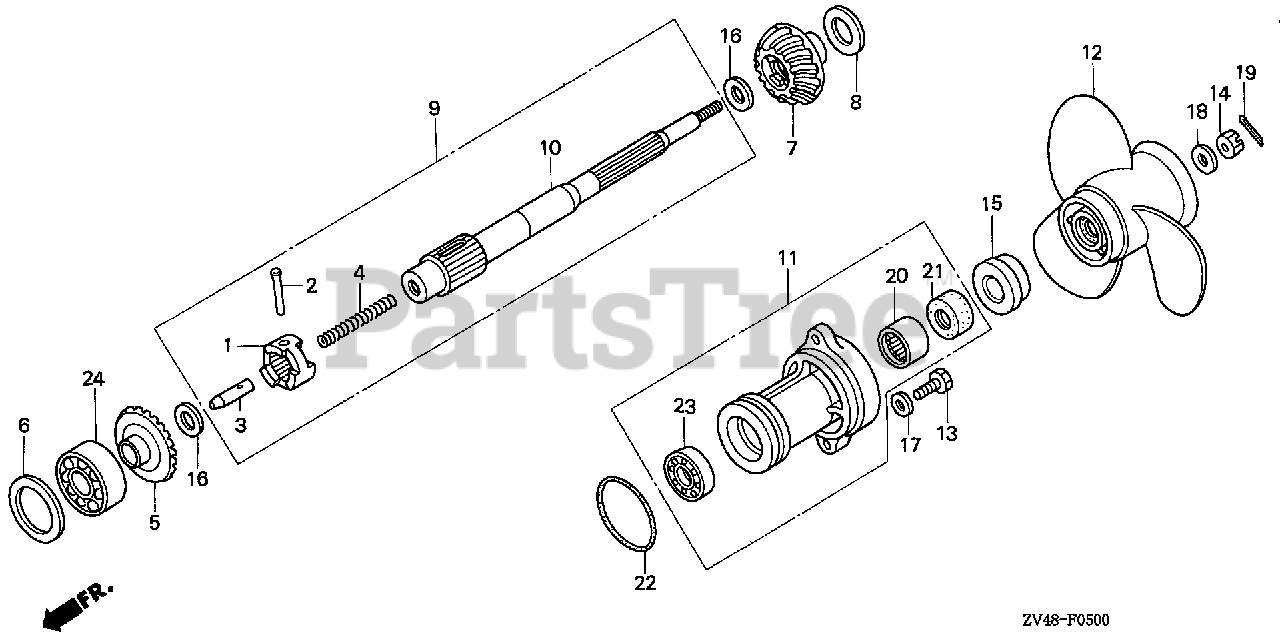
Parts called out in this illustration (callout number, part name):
1	SHIFTER, CLUTCH
2	PIN, SHIFTER (4X35)
3	SLIDER, SHIFT
4	SPRING, SHIFT
5	GEAR, FR. BEVEL (27T)
6	SHIM (40MM) (0.08MM) (A)
6	SHIM (40MM) (0.10MM) (B)
6	SHIM (40MM) (0.12MM) (C)
6	SHIM (40MM) (0.15MM) (D)
7	GEAR, RR. BEVEL (27T)
8	SHIM A, GEAR (0.10MM)
8	SHIM B, GEAR (0.15MM)
9	SHAFT, PROPELLER
10	SHAFT, PROPELLER
11	HOLDER ASSY., PROPELLER SHAFT *NH282MU* (OYSTER SILVER METALLIC-U)
12	PROPELLER, THREE-BLADE (9-1/2X9-1/2) *NH283* (STIN GRAY)
13	BOLT, HEX. (6X20)
14	NUT, CASTLE (10MM)
15	WASHER, PROPELLER THRUST
16	WASHER (17MM)
17	WASHER, PLAIN (6MM)
18	WASHER (10MM)
19	PIN, SPLIT (3MM)
20	BEARING, NEEDLE (17X23X12)
21	SEAL, WATER (17MM) (NOK)
22	O-RING (58X3) (ARAI)
23	BEARING, RADIAL BALL (6005)
24	BEARING, RADIAL BALL (6205)
